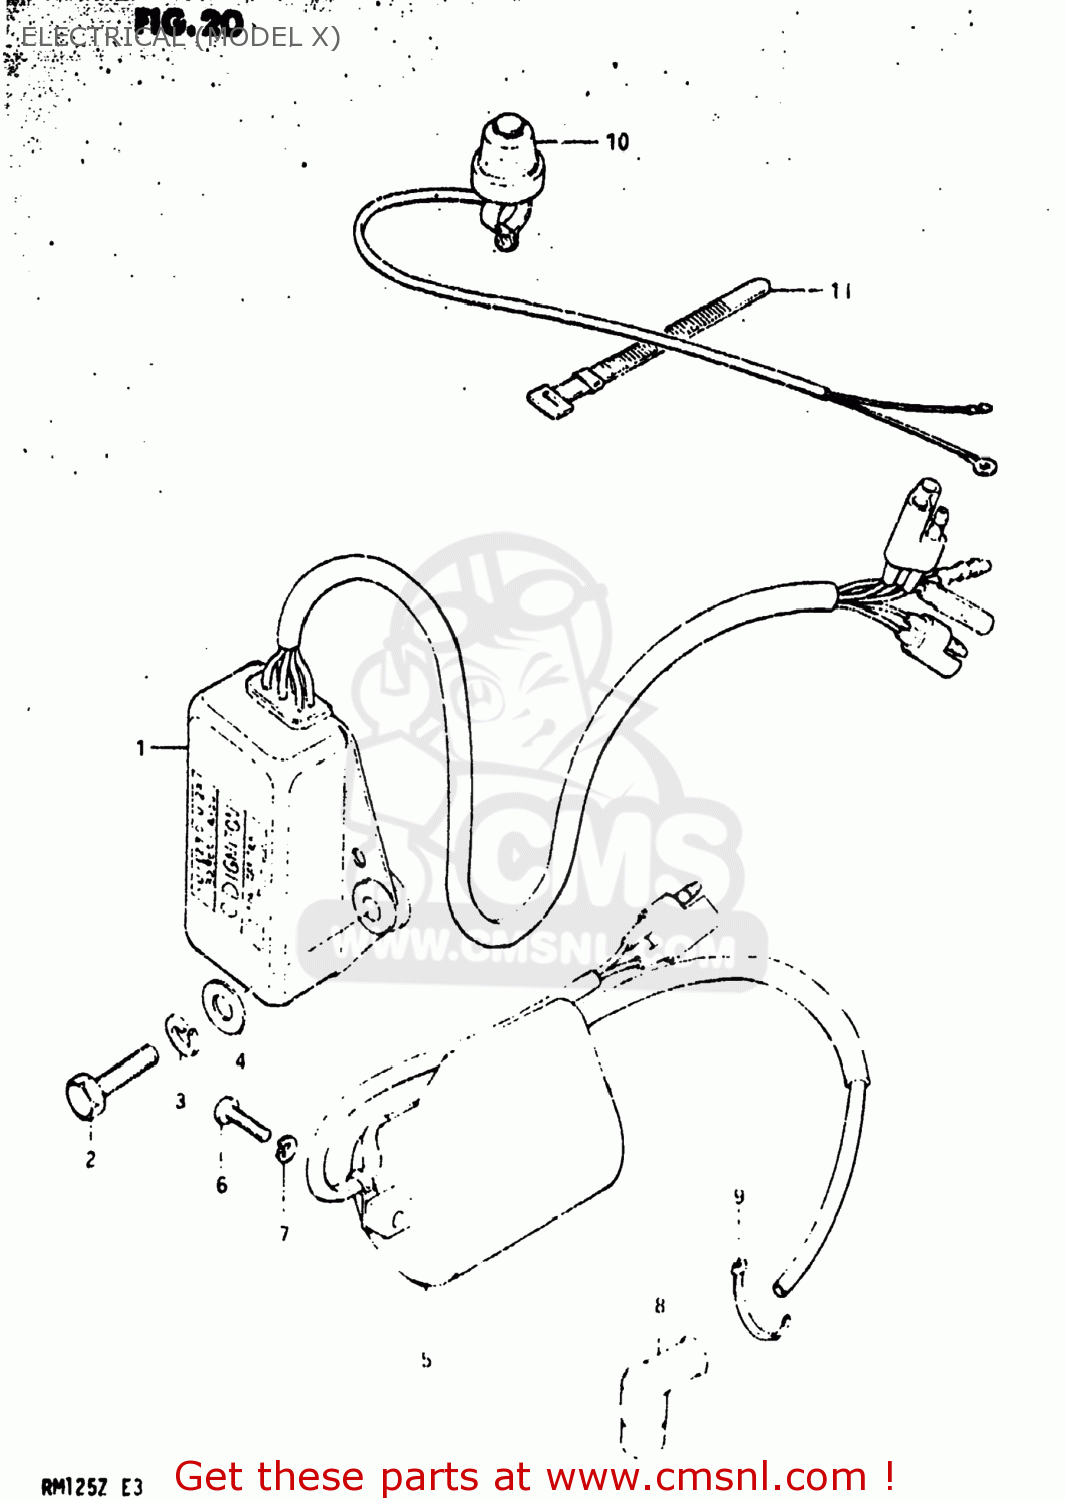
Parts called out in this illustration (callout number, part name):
1	CDI UNIT
2	BOLT
3	LOCK WASHER
4	WASHER(6.5X16X1.2)
5	COIL ASSY,IGNITION
6	SCREW 5X20
7	LOCK WASHER
8	CAP,SPARK PLUG
9	CLAMP
10	SWITCH ASSEMBLY
11	CLAMP(L:120)
